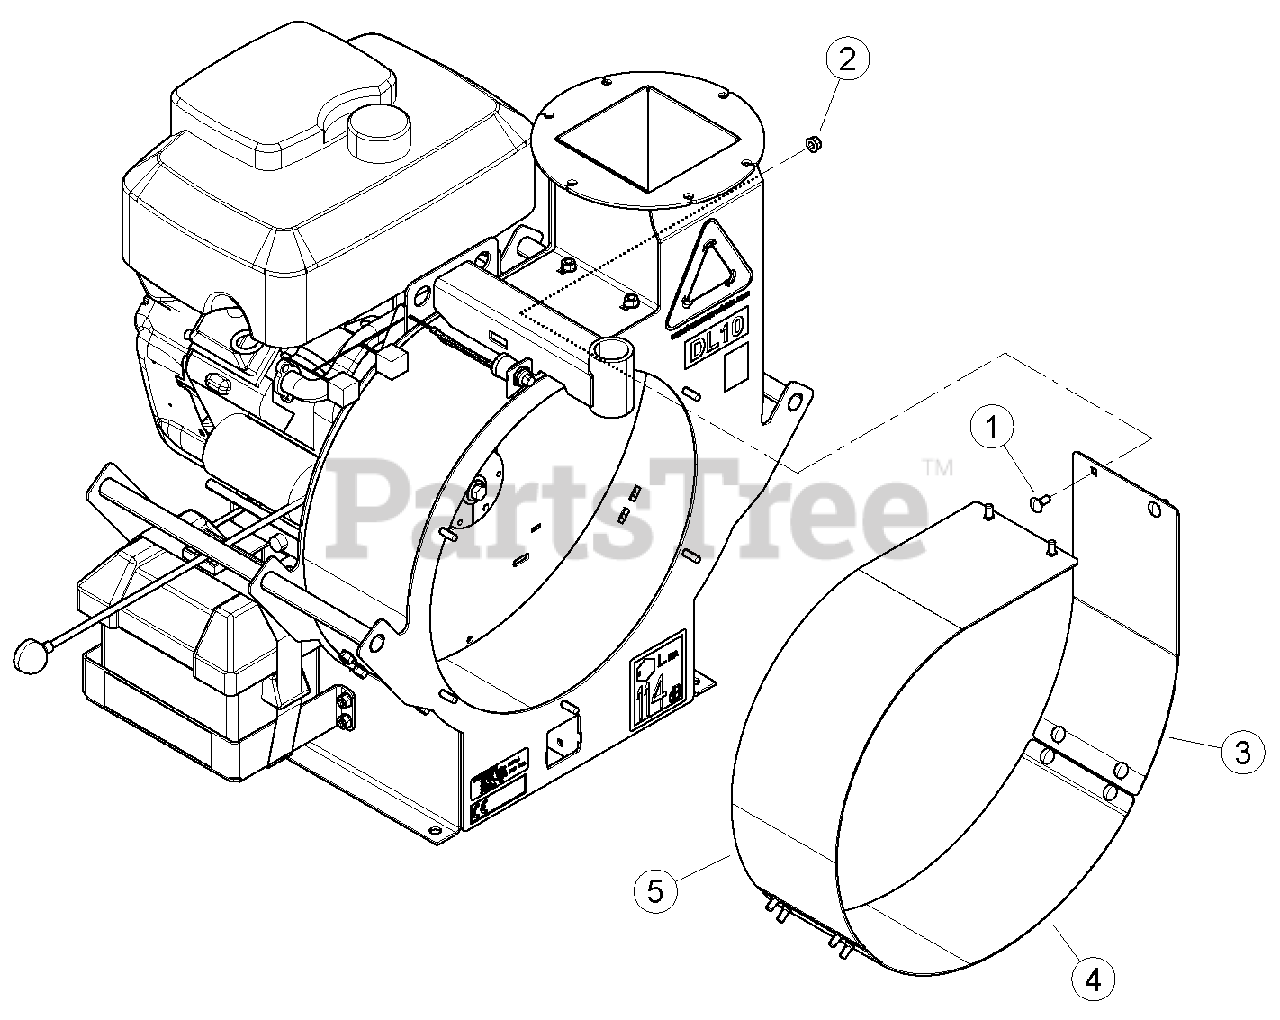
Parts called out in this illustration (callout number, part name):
1	BOLT, 5/16X3/4 GR5 NC ZP CRG
2	NUT, 5/16-18 NYLOCK FLANGE
3	LINER, WEAR RIGHT
4	LINER, WEAR MIDDLE
5	LINER, WEAR LEFT
